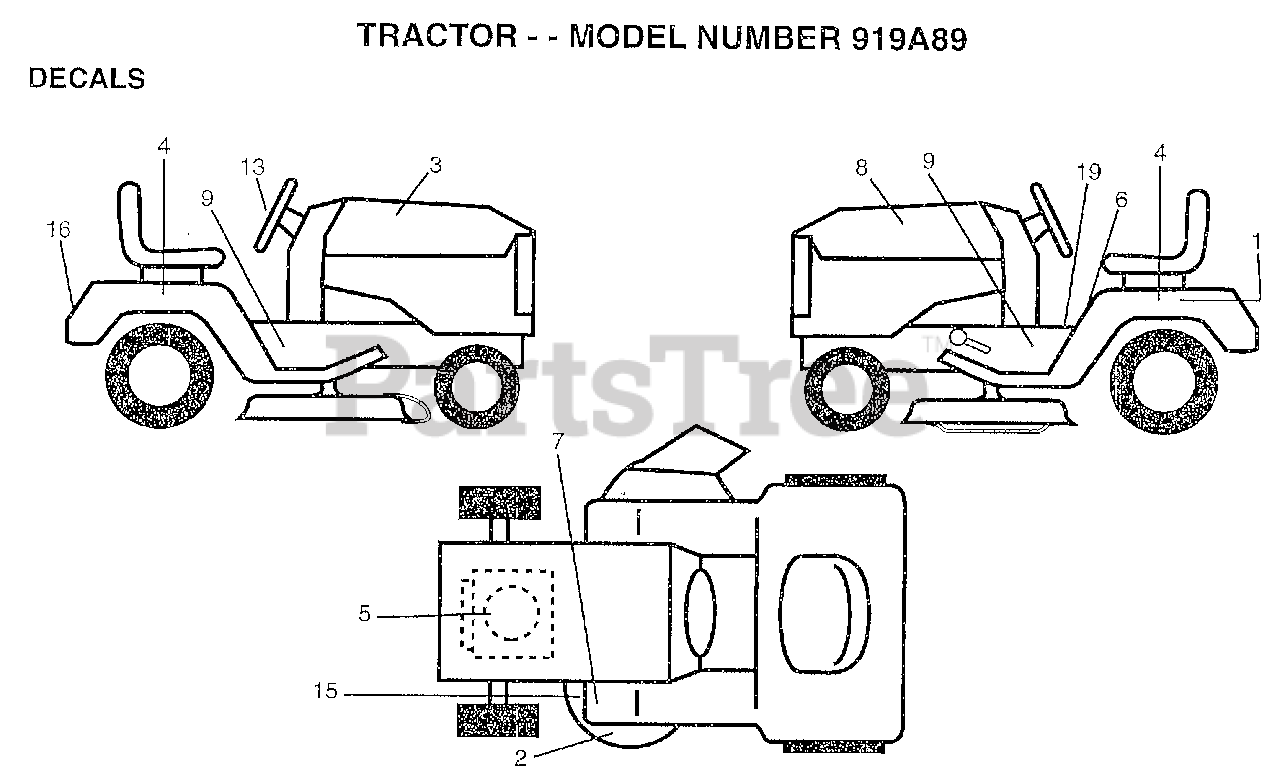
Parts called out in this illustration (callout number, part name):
1	DECAL.BATRY.3-3908
2	DECAL DECK WIZ +
3	DECAL.HOOD.RH
4	DECAL.FENDER.WIZ
5	DECAL HP ENGINE
6	"DECAL DANGER,FEND"
8	DECAL.HOOD.LH
9	"DECAL.CHASSIS.42"""
13	DECAL.INS.STRG.WL
15	"DECAL-SCHEM,BELT"
19	"DECAL INST,SADDLE"
